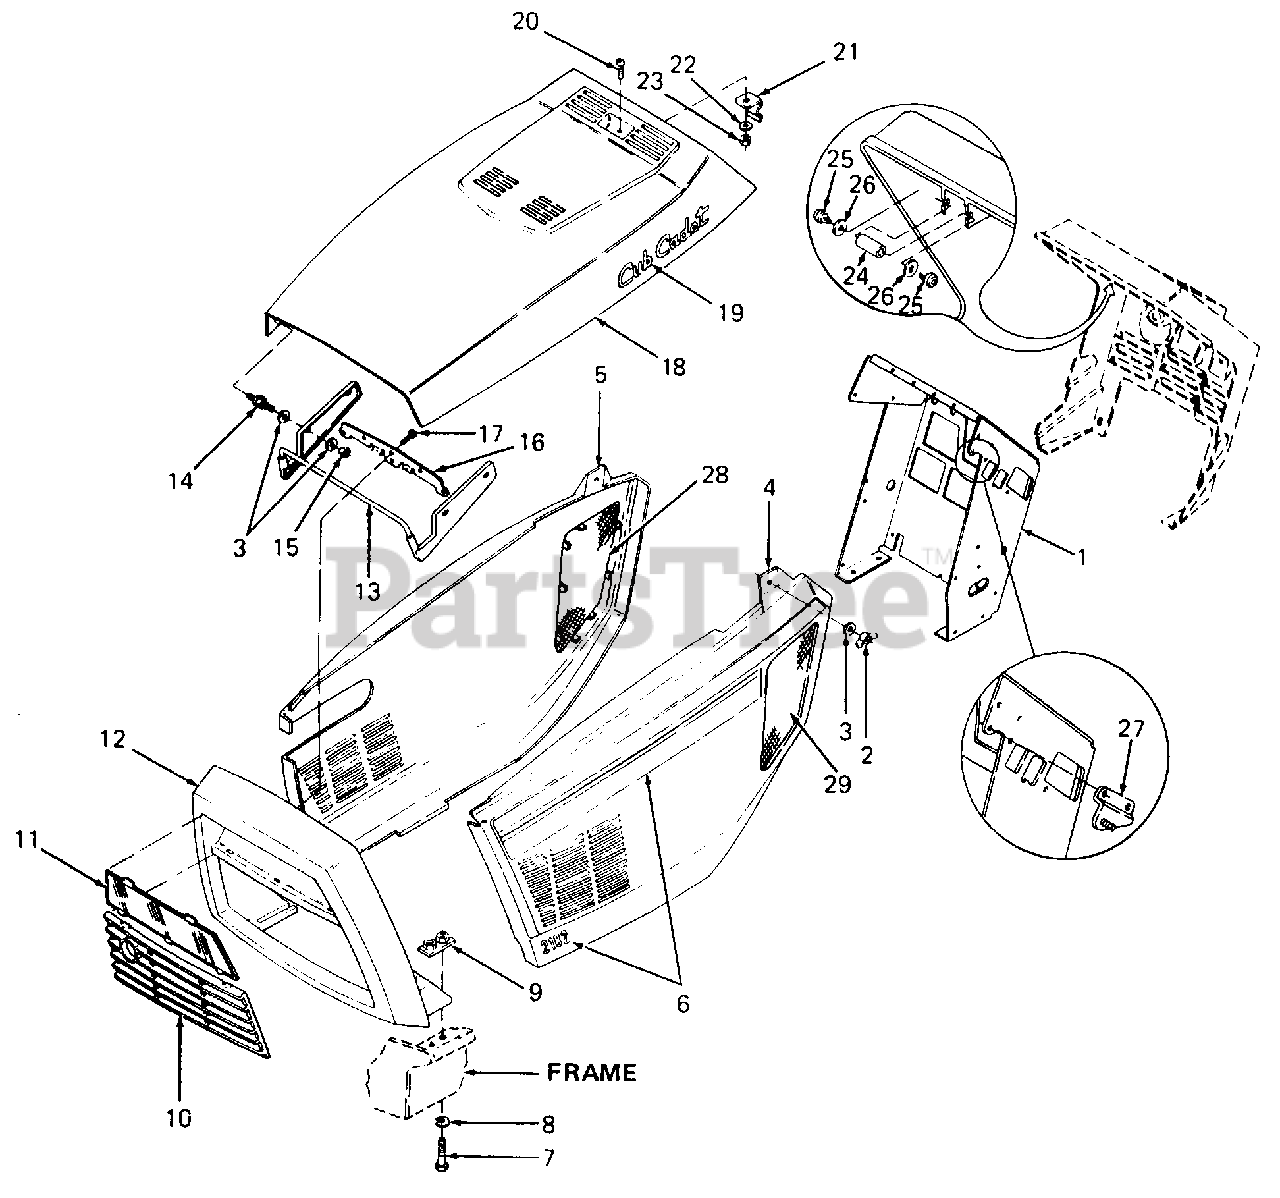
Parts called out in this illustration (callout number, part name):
3	Washer, Flat, .251 x .62 x .052 Thk
4	Panel, LH Side w/Slots
5	Panel, RH Side w/Cutout & Slots
6	Graphics Kit, LH Side Panel
7	Screw, Hex Cap, 5/16-18 x 1.0 Lg GR5
8	Washer, Lock, 5/16
9	Retainer, Grille Housing
10	Grille, Insert
11	Grille, Lens
12	Grille w/Label
15	Nut, Hex Patch Lock, 1/4-20
18	Hood
19	Graphic, Cub Cadet Script w/Studs
20	Screw, Truss Hd Mach, #8-32 x .38 Lg
21	Clip, Hood Latch
22	Washer, Flat, .16 x .38 x .045 Thk
23	Nut, Hex Keps, #8-32
24	Pin, Latch
25	Screw, Phillips Hd Truss Mach, 1/4-20 x .50 Lg
26	Washer, Flat, .285 x 1.25 x .060 Thk
